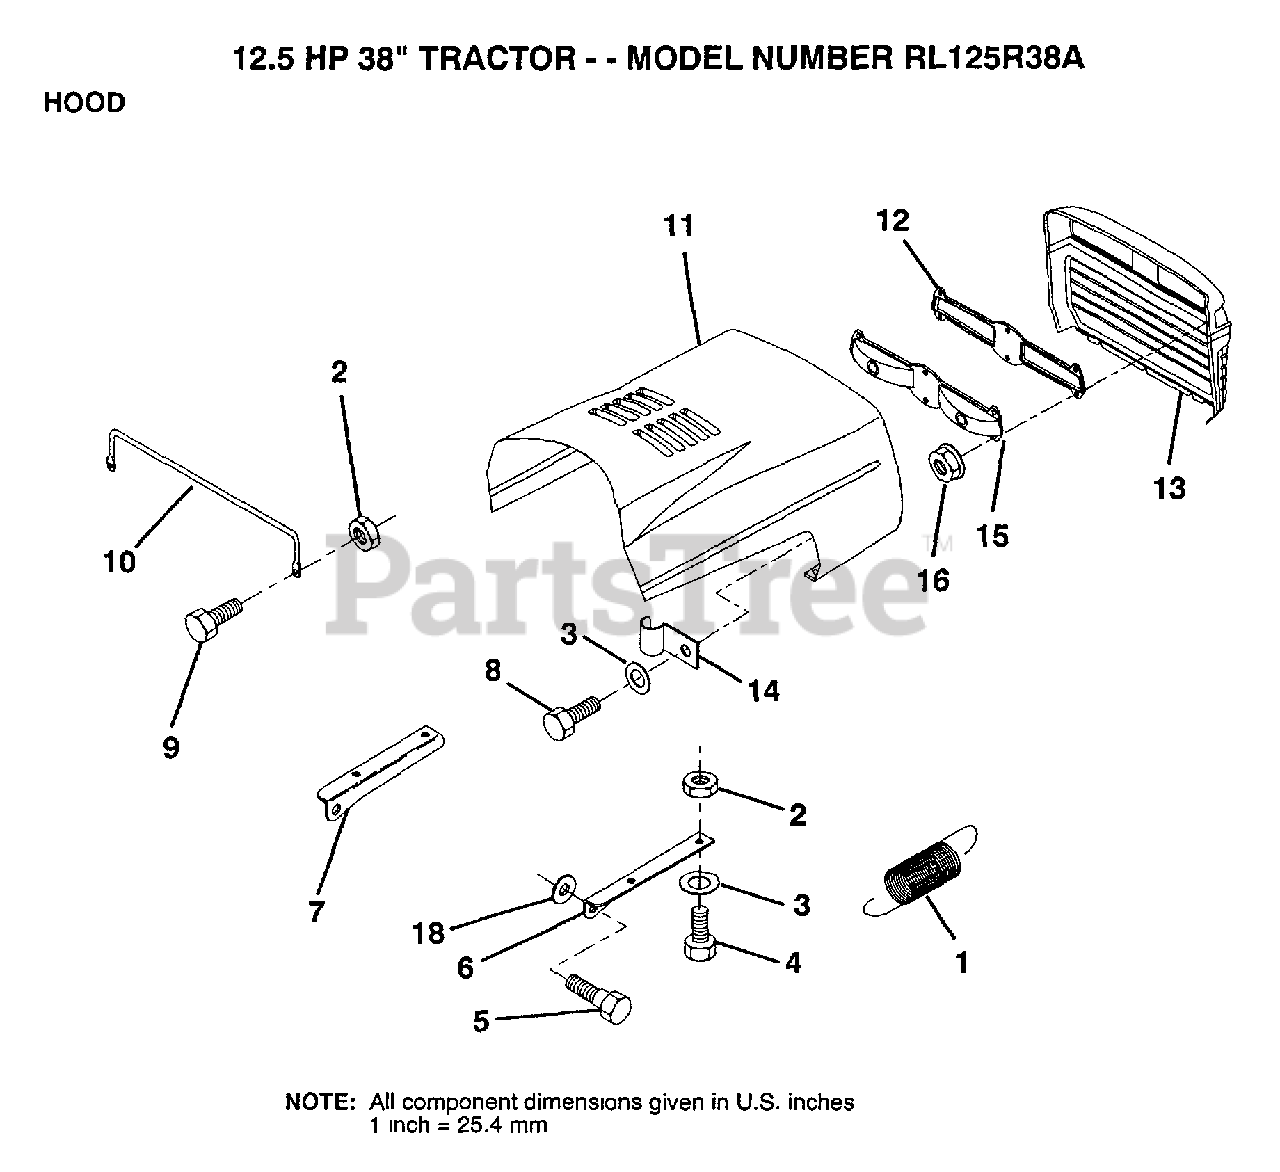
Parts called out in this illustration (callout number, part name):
1	EXT SPRING
2	NUT
3	WASHER
4	BOLT
6	BRKT HOOD RH
7	BRKT HOOD LH
10	"BRACE,HOOD"
11	HOOD
14	CLIP T
16	NUT
17	WASHER PM
18	WASHER
